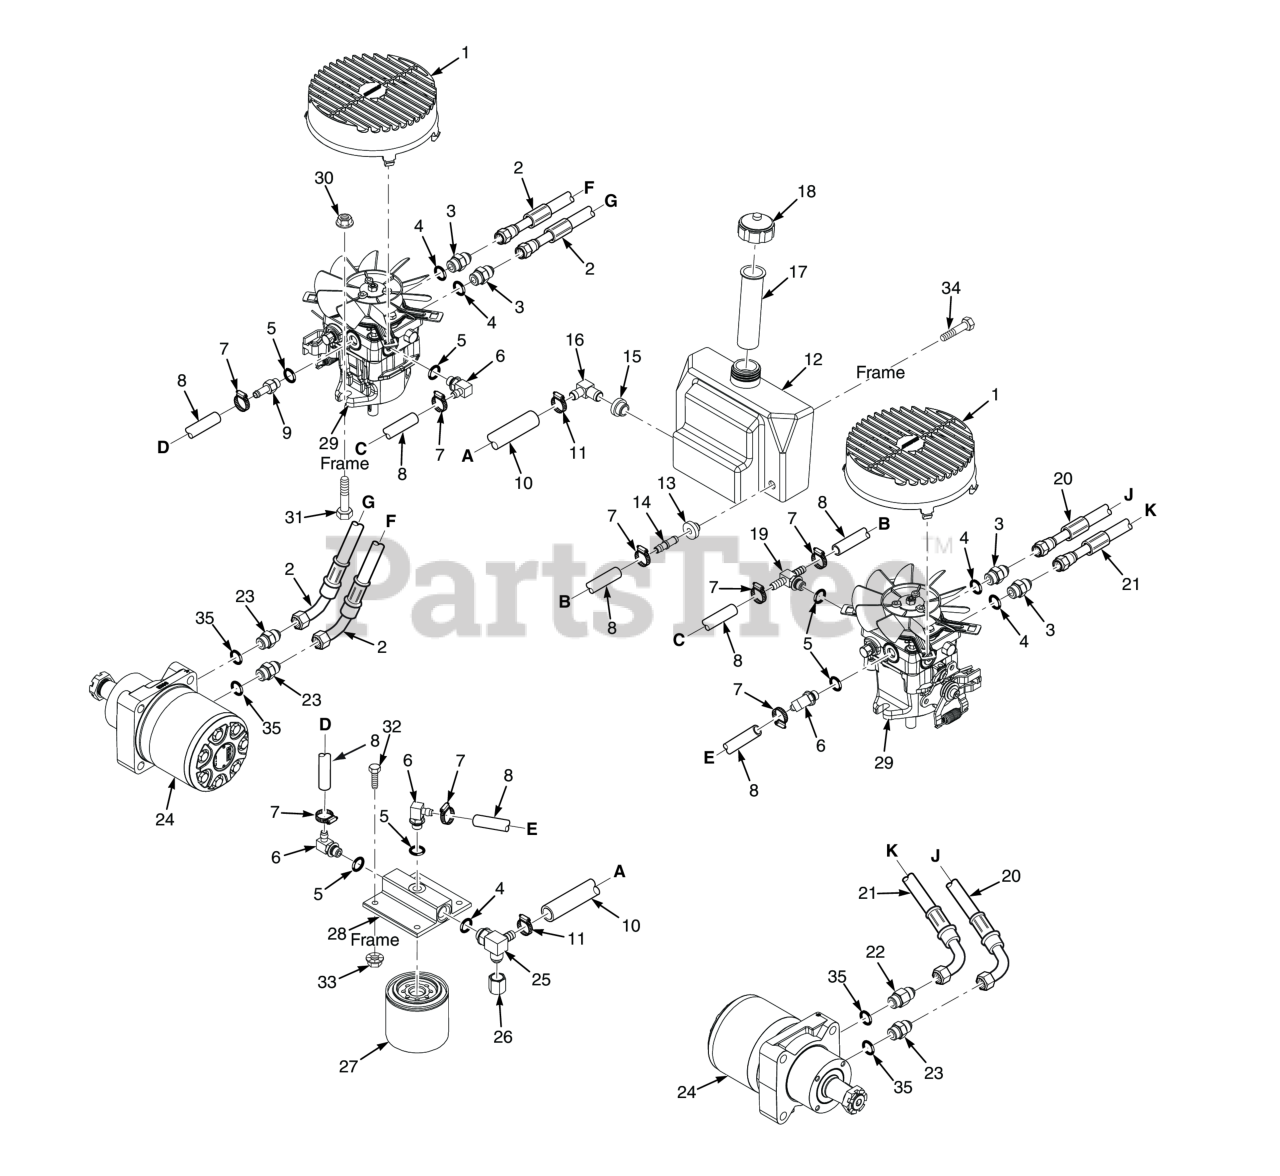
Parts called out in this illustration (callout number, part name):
1	Fan Cover, Pump
2	Hose Assembly
3	Union, 3/4"-16 JIC x 3/4"-16 O-Ring
4	"O" RING, 3/32 X 5/8" ID
5	"O" RING, 5/64 X 15/32 ID
6	Elbow, 90 Degree - 9/16" O-Ring x 3/8" Hose
7	Clamp, .69" Max. / .25" Min. Dia.
8	Hose, 3/8" ID - 10-1/4" Long (Order By The Inch)
9	Fitting, 9/16" O-Ring x 3/8" Hose
10	Hose Assembly, 1/2" ID (Oil Reservoir to Filter Base)
11	Clamp, Cable 3/4" I.D.
12	Hydraulic Tank Assy
13	Bushing, 0.56" Dia. Viton
14	Fitting, Straight
15	Bushing, 0.78" Dia. Viton
16	Fitting, 90 Degree - 1/2" Hose
17	Insert, Filler Neck
18	CAP, HYDRAULIC TANK
19	Tee Fitting, O-Ring to Barb
20	Hose Assembly
21	Hose Assembly
22	Fitting, 1/2" JIC x 5/8" O-Ring (LH Wheel Motor - Upper Port Only)
23	TUBE UNION, 3/4-16 JIC TO 7/8-14 "O" RING
24	Wheel Motor, Parker
25	Tee, 3/4" O-Ring x JIC x 1/2" Hose
26	CAP, 3-4-16 JIC
27	OIL FILTER, SPECIAL
28	Filter Head Assembly
29	Pump, LH (PK-3KCC-GA1F-XXXX)
30	Nut, Flange Elastic Stop Nut, 3/8-16
31	Bolt, Hex Head 3/8-16 x 1-1/2" B&S 32BV
32	BOLT, SERRATED FLANGE HEX HEAD 5/16-18 X 3/4"
33	Nut, Serrated Flange 5/16-18 (Right Front Engine Mounting, Briggs and Kohler Only)
34	CAP SCREW, 5/16-18 X 1/2" SERRATED FLANGE HEX
35	"O" RING, 3/32 X 3/4 ID
